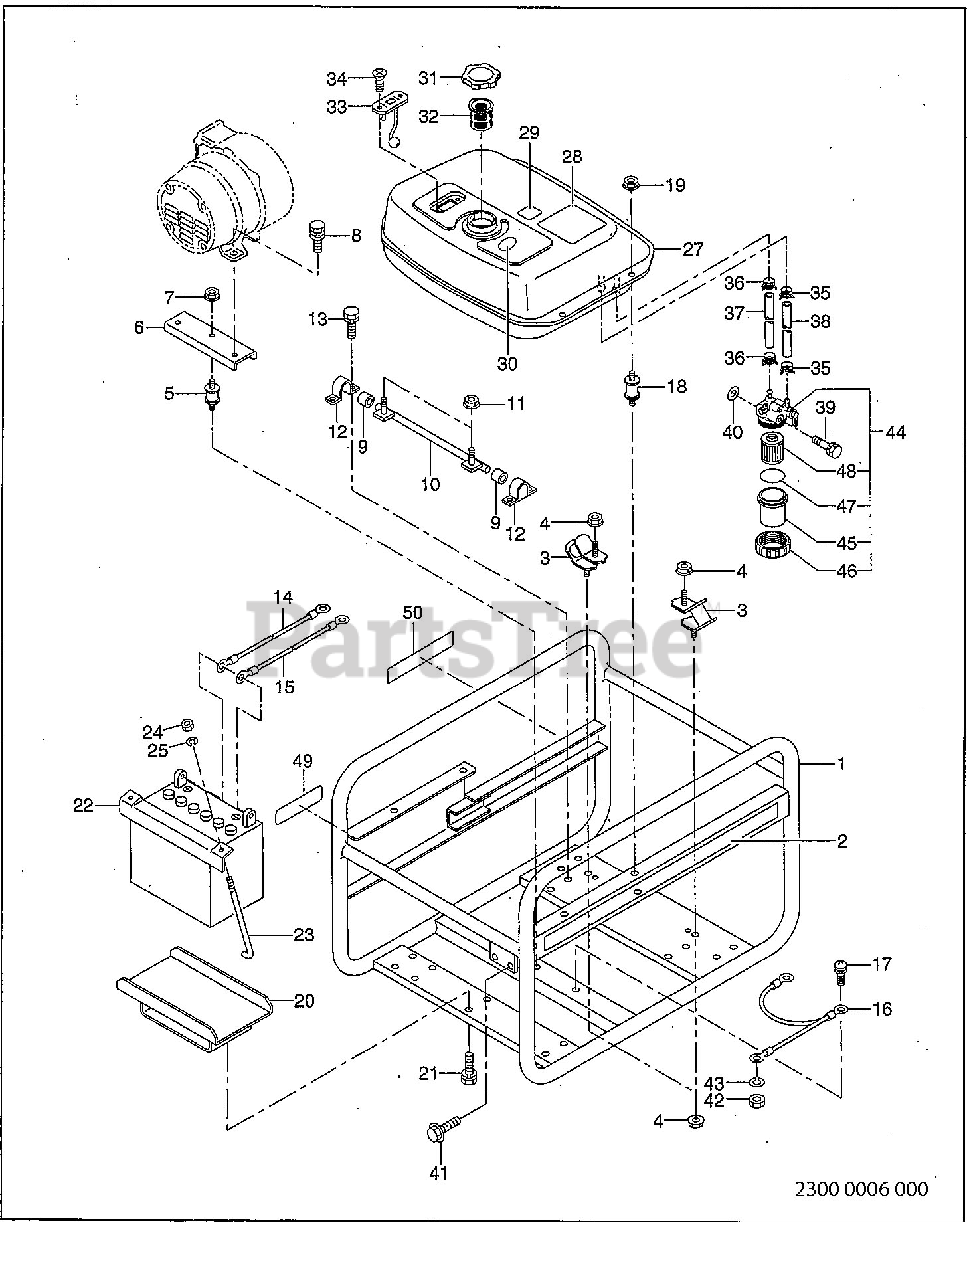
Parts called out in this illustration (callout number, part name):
1	PIPE FRAME ASSY
2	LABEL (RGD3300N)
6	GENERATOR BASE ASSY
8	BOLT and WASHER ASSY
10	SHAFT (stopper) ASSY
13	BOLT and WASHER ASSY
14	BATTERY WIRE(+)
15	BATTERY WIRE(-)
17	SCREW and WASHER ASSY
20	BATTERY BASE ASSY
21	BOLT and WASHER ASSY
22	BATTERY STAY ASSY
23	BATTERY BOLT ASSY
27	FUEL TANK ASSY
28	LABEL (SYMBOL-TANK)
29	LABEL (OIL CAUTION)
30	LABEL (LIGHT OIL)
31	FUEL TANK CAP ASSY
33	FUEL GAUGE ASSY
34	SCREW, counter head
37	RUBBER PIPE (6X12X140mm)
38	RUBBER PIPE (4.5X9X150mm)
39	BOLT and WASHER ASSY
44	FUEL FILTER ASSY
49	LABEL (SPEC. CE)
50	LABEL (HOT & GAS)
